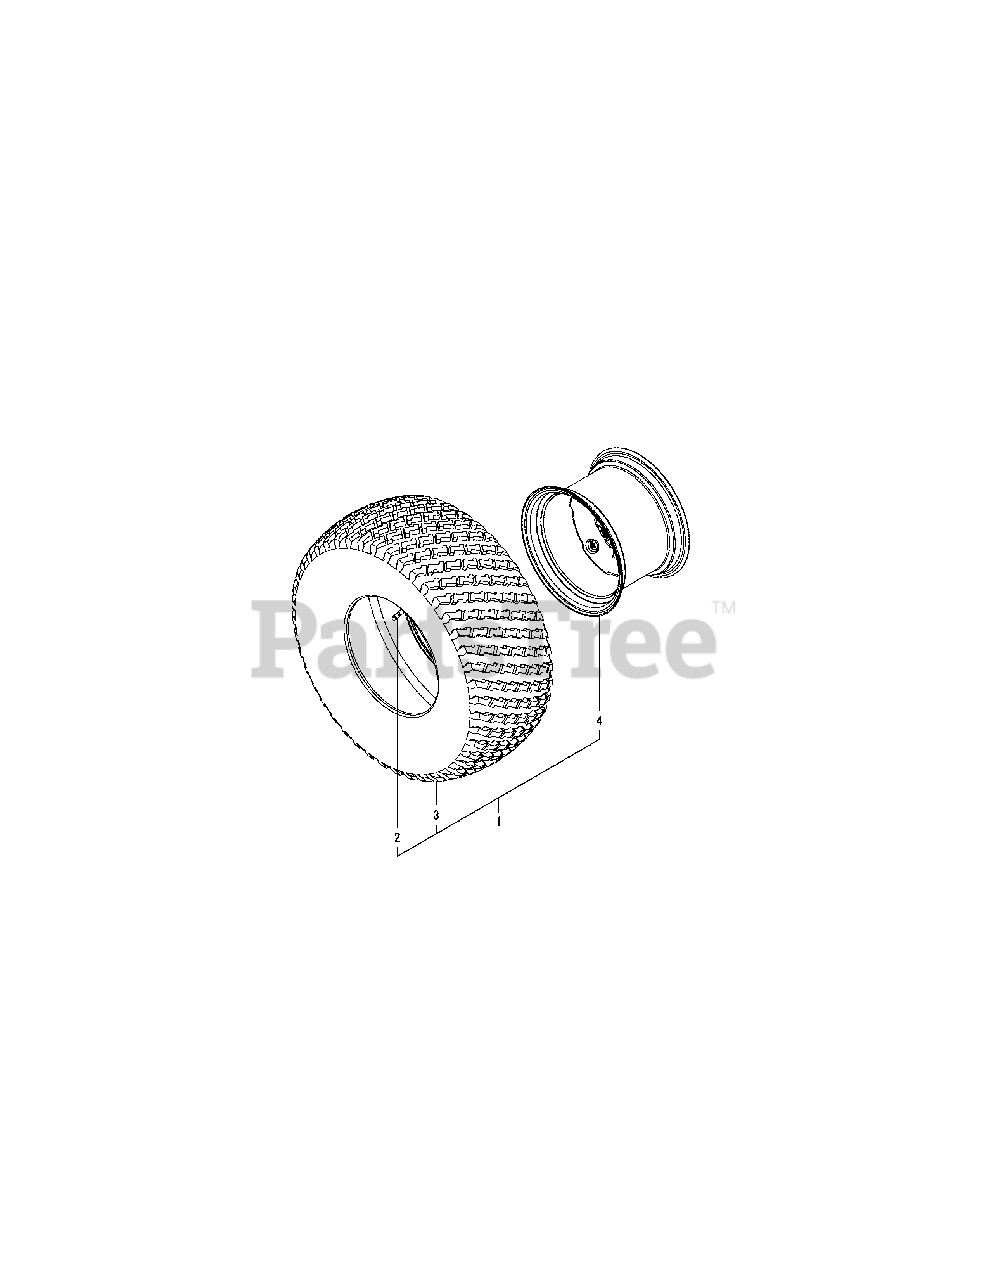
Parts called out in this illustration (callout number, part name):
1	R3 TIRE ASM,WHEEL
2	VALVE, REAR TIRE
3	R3 TIRE 44X18.00-20, TURF
